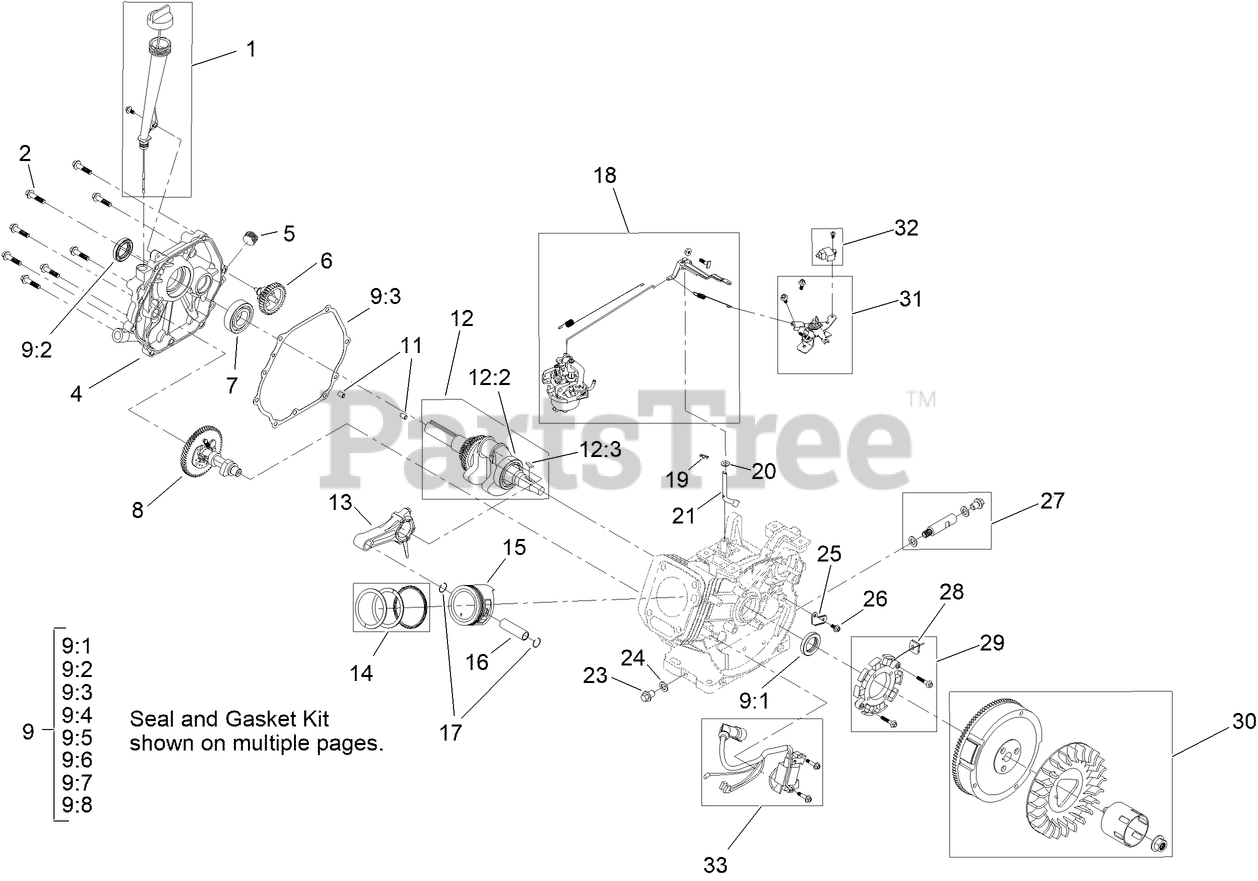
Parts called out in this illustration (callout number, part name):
1	OIL FILL KIT
2	SCREW-HHF
4	COVER-CRANKCASE
5	PLUG-DRAIN
6	GOVERNOR GEAR ASM
7	BEARING-MAIN
8	CAMSHAFT ASM
9	SEAL AND GASKET KIT
9:1	SEAL-OIL
9:2	SEAL-OIL
9:3	GASKET-COVER, CRANKCASE
9:4	GASKET-HEAD, CYLINDER
9:5	GASKET-COVER, VALVE
9:6	GASKET-EXHAUST
9:7	GASKET-CARBURETOR
9:8	GASKET-CARBURETOR
11	PIN-DOWEL
12	CRANKSHAFT ASM
12:2	BEARING-MAIN
12:3	KEY-WOODRUFF
13	CONNECTING ROD ASM
14	RING SET, PISTON
15	PISTON
16	PIN-PISTON
17	CLIP-PIN, PISTON
18	COMPLETE GOVERNOR KIT
19	PIN-HAIR
20	WASHER-PLAIN
21	SHAFT-GOVERNOR
23	SCREW-HHF
24	WASHER-PLAIN
26	SCREW-HHF
27	DRAIN PLUG KIT
28	GROMMET-RUBBER
29	STATOR KIT
30	FAN AND FLYWHEEL KIT
31	THROTTLE CONTROL KIT
32	KILL SWITCH KIT
33	IGNITION KIT
